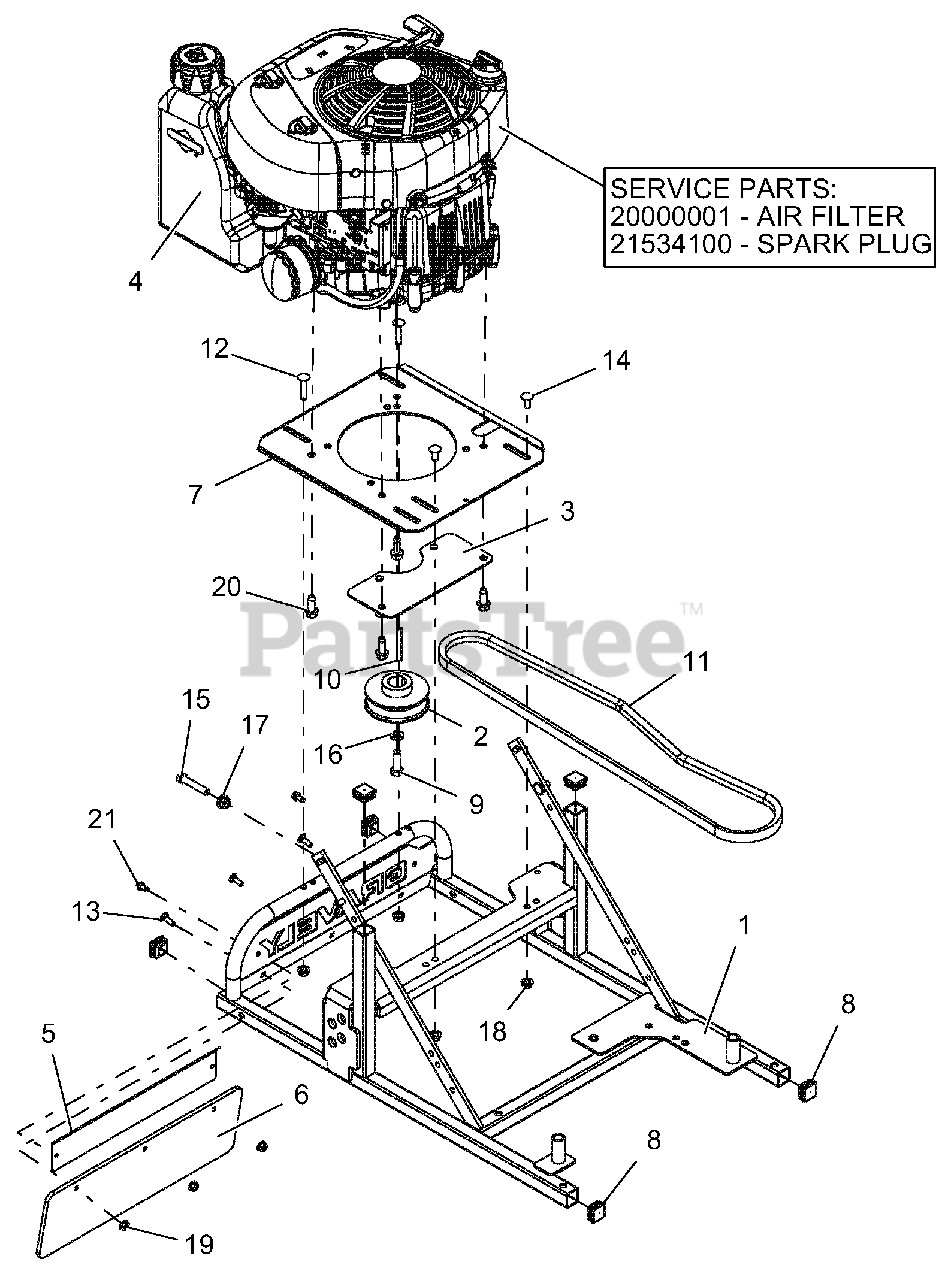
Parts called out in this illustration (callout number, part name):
1	WLDMT, HIGH WHL MWR FRAME
2	WMT-SHEAVE, ENGINE HWM INTEK
3	WLDMT, HWM ENGINE BELT FINGER (BLACK)
4	ENGINE, BRIGGS -10.5HP INTEK CARB
5	BACKER, GRAVELY
6	GUARD, RUBBER DEBRIS
7	PLATE, ENGINE (RED)
8	CAP PLUG FOR 1" TUBE 14GA
9	BLT, HEX .44-20X1.25 GR5 YWZC
10	KEY, .25X.25X2.25
11	V-BELT, 5L-WRAPPED
12	BLT-RDHDSQNK .31-18X1.50 G5 YWZC
13	BLT-RDHDSQNK .25-20X.75 G5 YWZC
14	BLT-RHDSSQNK .31-18X.75 G5YZ
15	BLT-HEX .38-16X2.00 FTH GR5 YWZC
16	WSHR-LK .44X.109 REG YWZC
17	NUT-LK-NYL-FLG .38-16 YWZC
18	NUT, LK-TOP-FLG .312-18 YWZC
19	NUT, LK-TOP-FLG .25-20 YWZC
20	SCR-TAP .38-16X1.00 HWH TR YZ
21	SCR-TAP .25-20X.50 HWH TR YWZ
22	AIR FILTER
23	SPARK PLUG
